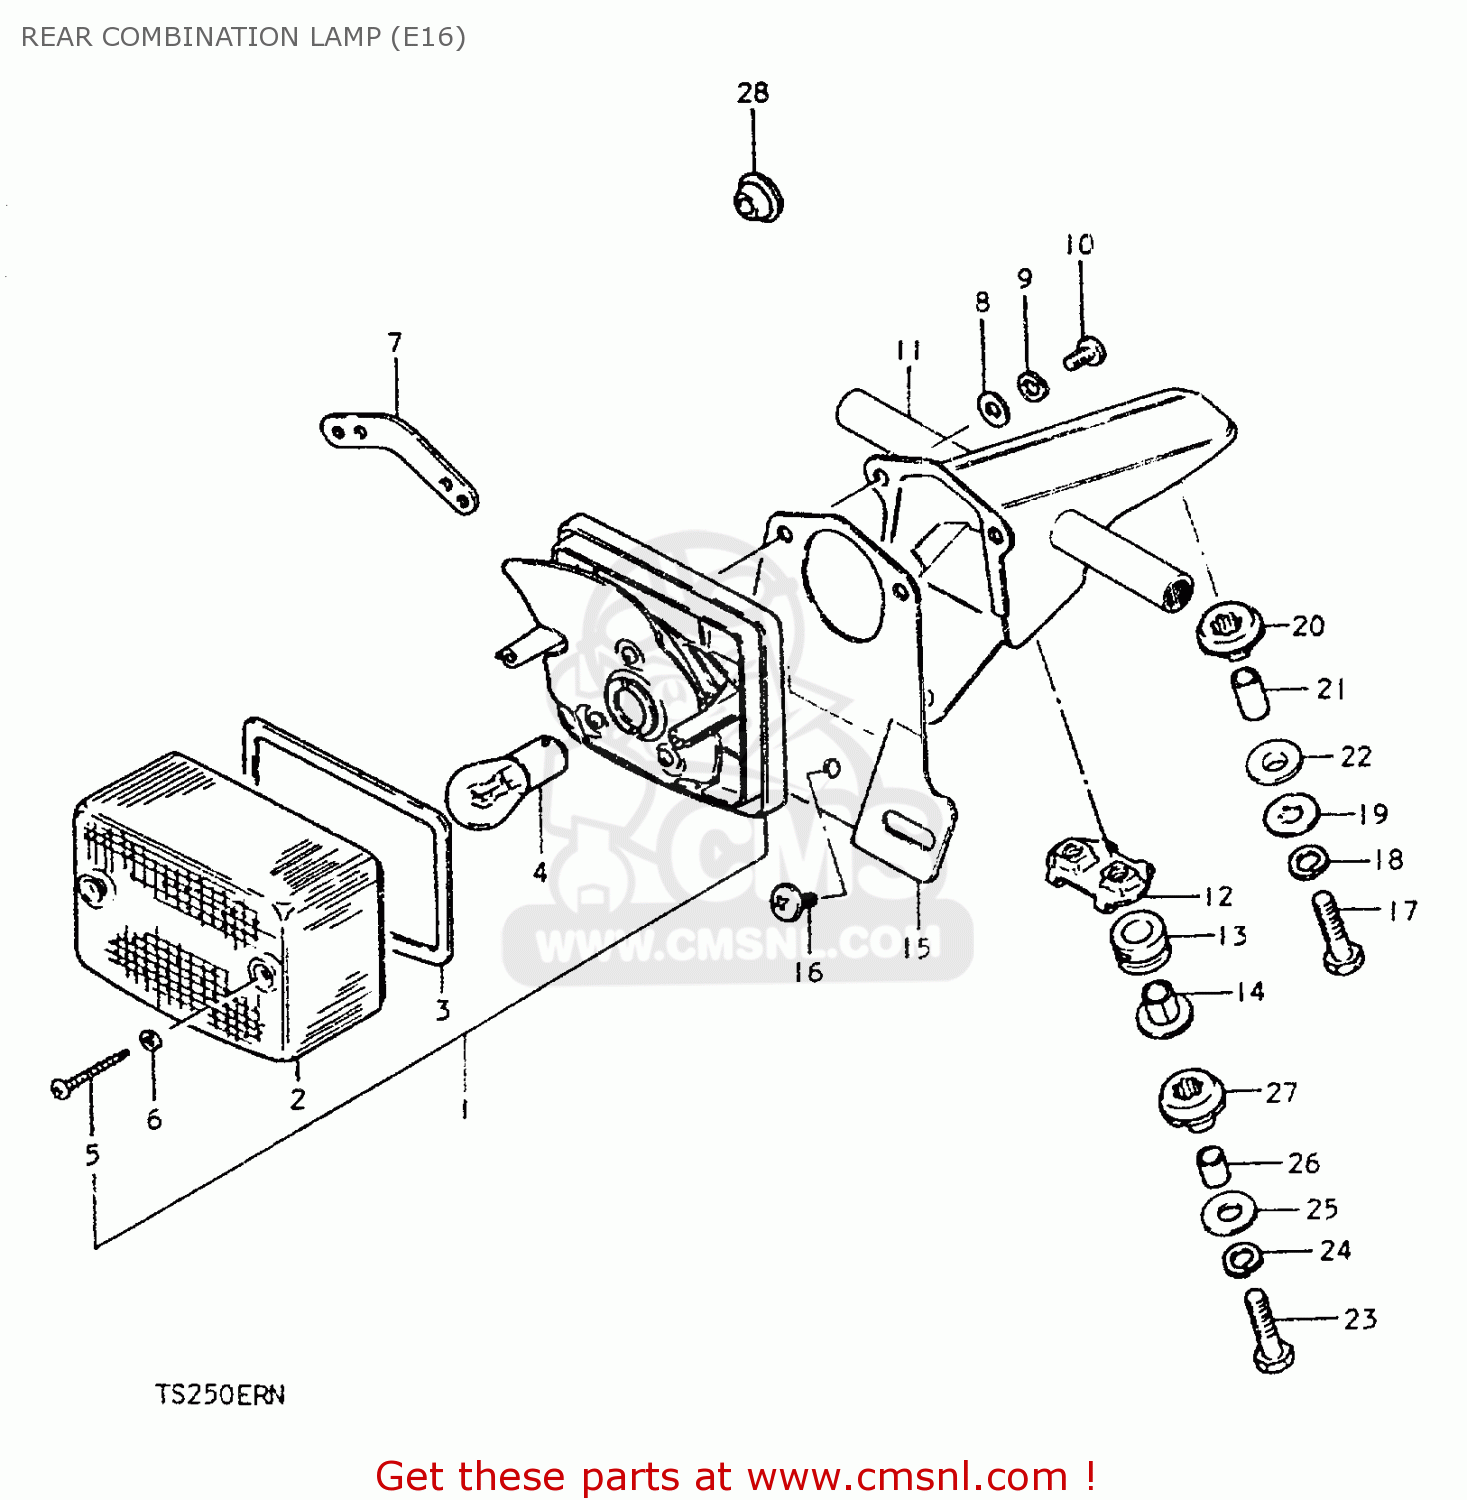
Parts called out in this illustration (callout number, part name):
1	LAMP UNIT, TAIL
2	LENS
3	GASKET (NAS)
4	BULB (6V,21/5W)
5	BOLT
6	GASKET (NAS)
7	PLATE,REAR COMBINATION LAMP
8	WASHER,5MM
9	WASHER,LOCK
10	SCREW
11	BRACKET ASSY
12	PLATE
13	CUSHION
14	SPACER
15	PLATE, LICENSE
16	SCREW
17	BOLT
18	LOCK WASHER
19	WASHER (6.5X20X1.2)
20	CUSHION
21	SPACER
22	CUSHION
23	BOLT
24	LOCK WASHER
25	WASHER (6.5X20X1.2)
26	SPACER
27	CUSHION
28	GROMMET
